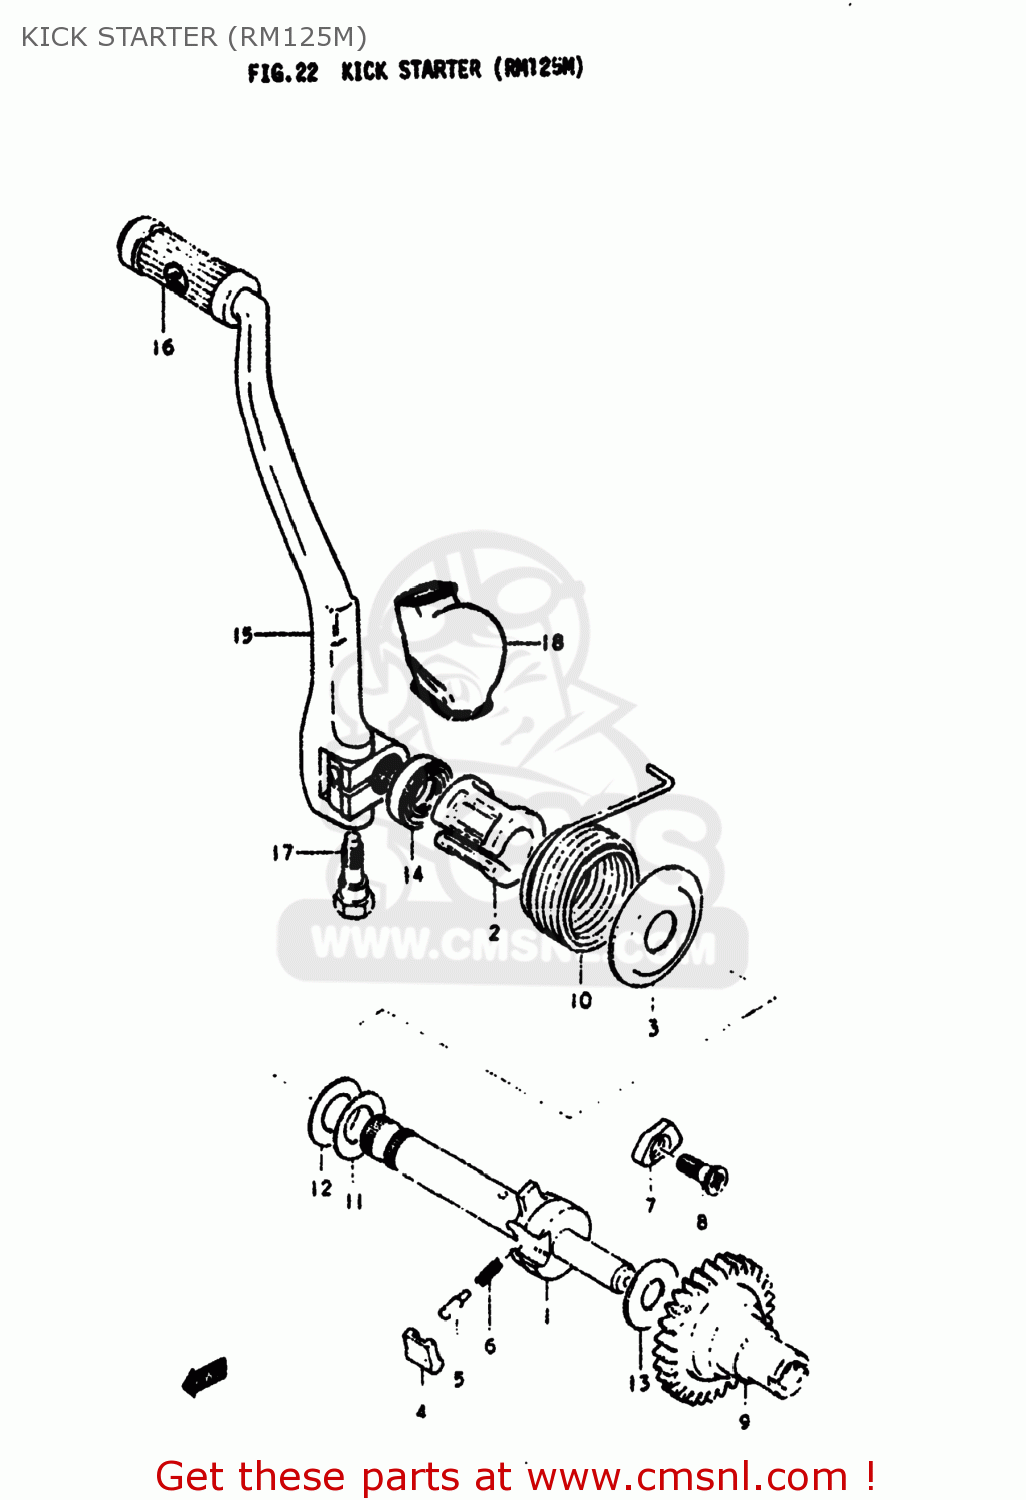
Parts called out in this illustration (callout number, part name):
1	SHAFT,KICK STARTER
2	GUIDE,KICK STARTER SFT SPRING
3	HOLDER,KICK STARTER SHAFT SPR
4	PAWL,KICK STARTER
5	PIN(5X15.5)
6	SPRING
7	LIFTER,KICK STARTER PAWL
8	SCREW(6X19)
9	GEAR,KICK STARTER DRIVE
10	SPRING
11	WASHER(16X30X0.5)
12	WASHER
13	WASHER
14	SEAL,OIL(16X30X8)
15	LEVER ASSY,KICK STARTER
16	RUBBER,KICK STARTER PEDAL
17	BOLT
18	COVER,KICK LEVER JOINT
